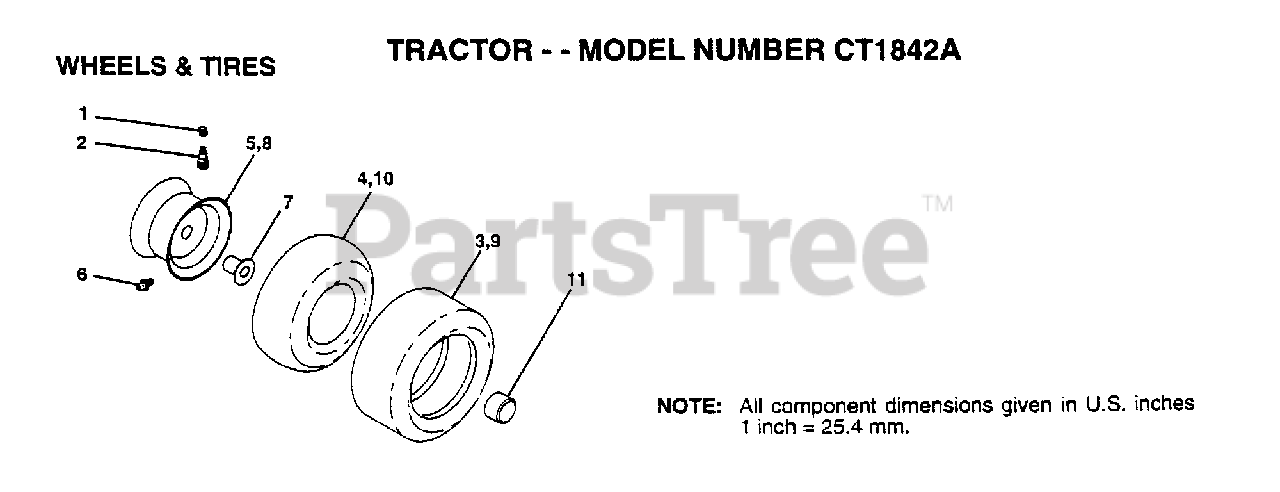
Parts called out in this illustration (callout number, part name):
1	VALVE CAP
2	VALVE STEM LT
4	TUBE.5.3/4.5/6
5	"RIM ASM 6"" FRT"
6	FITTING LT
7	"FLANGE, BEARING"
8	"RIM AS 8"" REAR"
9	TIRE.20X8-8
10	TUBE.18X9.5-8
11	HUB CAP
